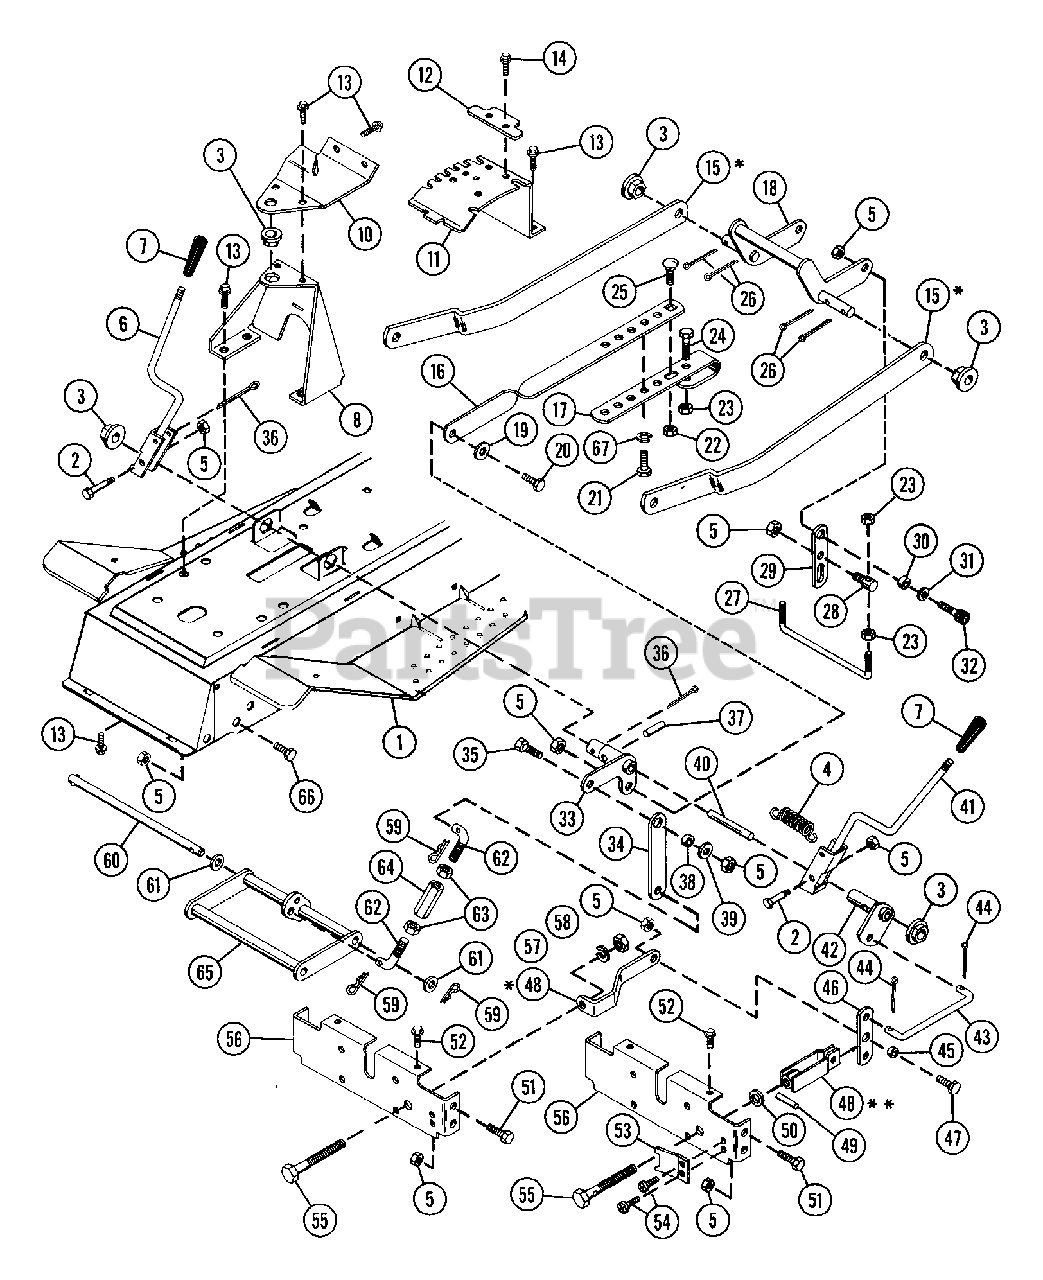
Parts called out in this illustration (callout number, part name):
1	FRAME
2	SHOULDER BOLT .436 X .912
3	FLANGE BUSHING
4	SG-TENS .092X.69X1.75 WLD 54
5	NUT-LK .312-18 GR A PL
6	MOWER HEIGHT LEVER
7	HANDLE
7	GRIP
8	STEERING SUPPORT
11	QUADRANT
13	BLT-SERHFWH .31-18X.50 PL
14	BLT-SERHFWH .25-20X.50 PL
15	POSITIONING ARM
16	LIFT STRAP
17	ADJUSTMENT STRAP
18	REAR MOWER HANGER
19	SPACER -SHLD .344X.500X.469
20	BLT-HEX .31-18X1.25 PL GR2
21	BLT-HEX .38-16X.75 PL GR2
22	NUT-LK-CTR .375-16 GR A PL
23	NUT-LK-JAM-CTR .375-16 PL
24	BLT-HEX .38-16X1.50 PL GR2
25	BLT-RDHDSQNK .38-16X.75 SHT PL
26	PIN-COTR .09X1.0 PL
27	ROD - REAR LIFT
28	ROD PIVOT
29	LINK - REAR LIFT
30	SPACER BUSHING .5 X .32 X .21
31	WSHR-FL-STL .344X1.125X.063PL
32	SCR-SKH .31-18X.75 BTNHD YWZC
33	MOWER LIFT ARM
35	BLT-HEX .31-18X.75 PL GR2
36	PIN-COTR .18X1.50 PL
37	PIN-ROLL .188X1.25
38	SPACER BUSHING .5 X .32 X .163
39	WSHR-FL-STL .323X.625X.062 PL
41	MOWER CLUTCH LEVER
42	CLUTCH ARM
43	LINK
44	PIN-COTR .09X.75 PL
45	GRILL
46	CLUTCH LINK
47	BLT-HEX .31-18X.88 PL GR2
48	ADJUSTMENT YOKE
48	FRONT ANCHOR
49	PIN-ROLL .188X1.00
50	WSHR-FL-STL .505X1.000X.062
51	BLT-HEX .31-18X.63 PL GR 2
52	SCR-TAP .250-20X.50 HXSLHDPL
53	LOCK SPRING
54	SCR-TAP 10-24X.25 CRSLPH PL 1A
55	CAP SCREW
55	BLT-HEX .50-13X1.25 PL GR2
56	MOWER ADJUSTMENT BRACKET
57	WSHR-LK .500X.151 HVY PL
58	NUT .50-13 PL
59	PIN-HAIR INT .08X.38X1.42 YWZC
60	HANGER PIN
61	WSHR-FL-STL .505X.880X.072 PL
62	LINK - FRONT LIFT
63	NUT-LK .375-16
64	NUT-CUPLG .375-16 PL
65	FRONT LIFT ARM
66	BLT-HEX .31-18X.50 PL GR2
67	WSHR-LK .375X.115 HVY PL
